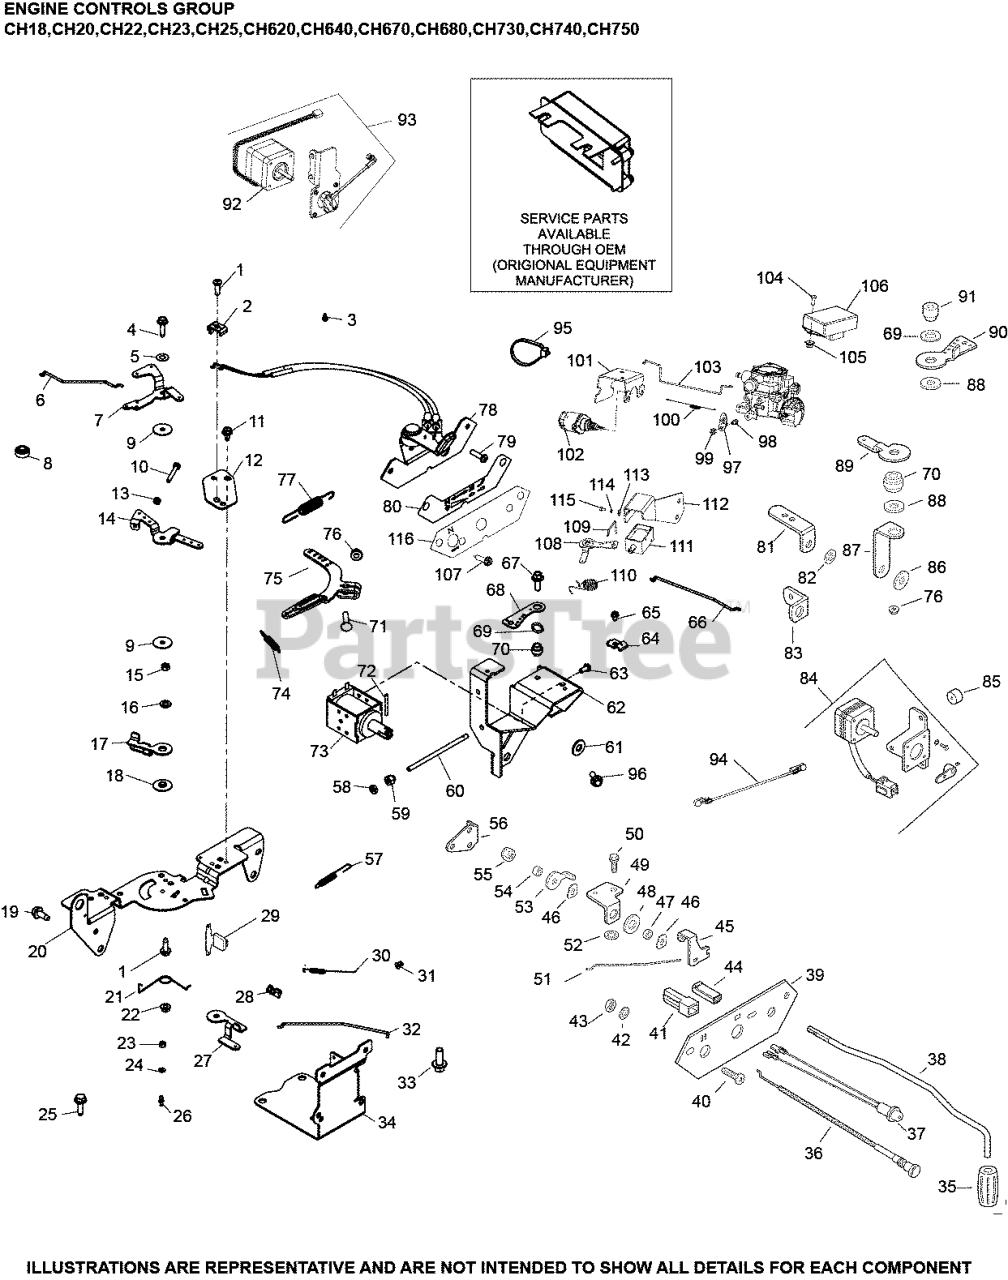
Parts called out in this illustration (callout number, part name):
1	SCREW,FLG THD FRM M5X0.8X16-(#25086398S)
2	CLAMP, CABLE
4	SCREW, FLG THD FRM M5X.8X20-(#25086399S)
5	WASHER, SPRING 1/4"
6	LINKAGE, CHOKE
7	LEVER, CHOKE
9	WASHER, FLAT 5.5 MM
10	SCREW, CAP M4X.7X30
11	SCREW, FLG THD FRM M5X.8X10
12	BRACKET, CABLE SUPPORT
13	NUT, M4X0.7
14	LEVER, THROTTLE CONTROL
15	NUT, FLG M5X.8
16	WASHER, SPRING LOCK 1/4"
17	LEVER,THROTTLE ACTUATOR-USE(24 090 65-S
19	SCREW,FLG THD FRM M6X1.0X16-(#25086397S)
20	BRACKET, CONTROL-USE 24 126 176-S
22	NUT, LOCK M5X.8
28	BUSHING, THROTTLE LINKAGE
30	SPRING, LINKAGE
31	BUSHING, LINKAGE RETAINING
32	LINKAGE, THROTTLE
50	SCREW, THREAD FORMING
57	SPRING, THROTTLE LIMITER
71	BOLT, RD HD SQ NECK M6X1.0X25
75	LEVER, GOVERNOR-USE 24 090 57-S
76	NUT, FLG M6X1.0
77	SPRING, GOVERNOR (BLACK)
78	CABLE ASSY, CONTROL - (#2422508S)
80	DECAL, CONTROL PANEL
107	SCREW, HEX WASHER HI-LO
